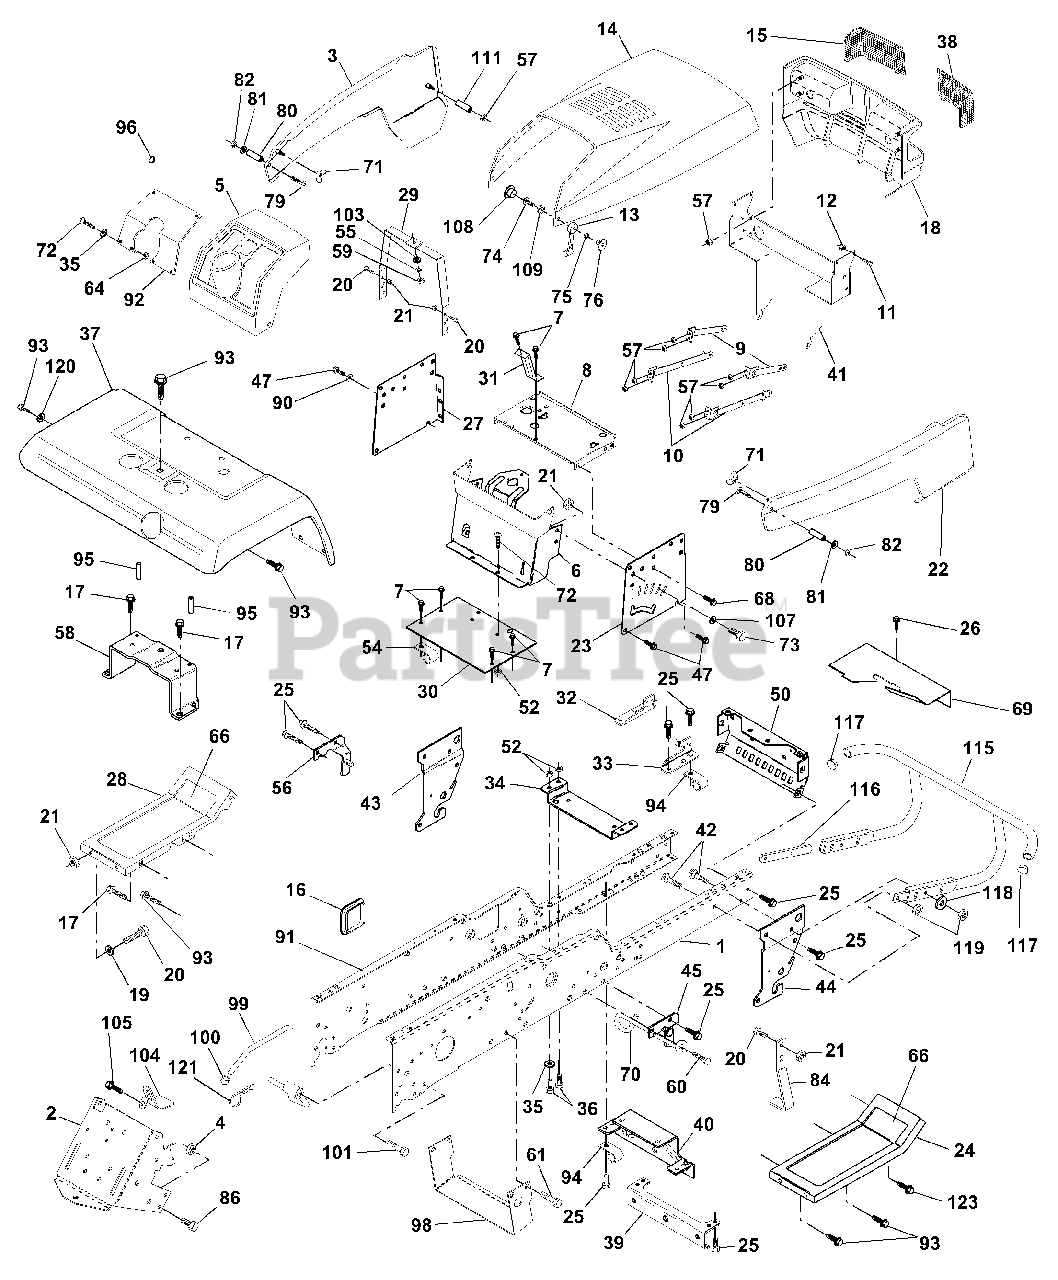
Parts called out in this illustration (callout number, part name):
1	Rail, Frame RH
2	Drawbar, Gt
3	Panel Asm., Side LH
4	Nut, Lock Hex 7/16 Unc
5	Dash, Plastic Black
6	Dash Asm., Lower
7	Screw, Thd Cut 1/4-20 x 1/2
8	Support, Battery
9	Strap, Asm. Hinge Front
10	Strap, Asm. Hinge Rear
11	Bolt Shoulder 1/4-20
12	Nut Crownlock 1/4-20
13	Latch, Chute Blk
14	Hood Asm., Pnt
15	Lens, Headlight LH
16	Cover, Access
17	Screw, Thdrol 3/8-16 x 3/4
18	Grille
19	Washer 13/32 x 13/16 x 12 Ga.
20	Bolt, Fin Hex 3/8-16 x 1
21	Nut, Lock Hex W/Wsh 3/8-16 Unc
22	Panel Asm., Side RH
23	Panel, Dash Side RH
24	Footrest, RH
25	Screw, Thdrol 3/8-16 x 3/4
26	Screw, Thdrol 5/16-18 x 3/4
27	Panel, Dash Side LH
28	Footrest, LH
29	Bracket, Support Dash
31	Brace, Support Steering
32	Bracket Asm., Frame Pivot Lh
33	Bracket Asm., Frame Pivot Rh
34	Bracket, Engine Support Rear
35	Washer 11/32 x 11/16 x 16 Ga.
36	Bolt, Fin Hex 5/16-18 x 3/4
37	Fender, Pnt.
38	Lens Headlight RH
39	Bracket, Axle Front
40	Bracket, Support Axle/Engine
41	Support Asm. Grille
42	Bolt, Carriage 3/8-16 x 1-1/4
43	Bracket, Spnsn Front Lh
44	Bracket, Spnsn Front Rh
45	Bracket Asm., Susp Chassis Rh
47	Screw Thdrol 3/8-16 x 1/2
50	Bracket, Chassis Front
52	Locknut, Hex W/Ins 5/16-18 Unc
54	Clip, Insulated
55	Washer 9/32 x 3/4 x 16 Ga.
56	Bracket Asm., Susp Chassis Lh
57	Nut Keps Hex 1/4-20
58	Bracket Asm., Fender
59	Nut Fin Hex 1/4-20
60	Screw Thdrol 3/8-16 x 1-1/4
61	Screw Thdrol. 3/8-16 x 3/4
62	Retainer Spring
64	Nut 5/16-18
66	Pad, Footrest
68	Screw, Thdrol 5/16-18 x 1/2
69	Shield, Heat
70	Guide, Belt Mid Span
71	Nut, Plastic Locking Wing 1/4-20
72	Screw, Mach Trhd 5/16-18 x 3/4
73	Bolt, Fin Hex 3/8-16 x 1 Gr. 5
74	Screw, Machine #10-24
75	Washer, Lock #10
76	Nut, Weld #10-24
79	Screw, Machine #10-24 x 1/4
80	Spacer, Split
81	Washer 7/32 x 1/2 x 18 Ga.
82	Nut #10-24
84	Stop, Over Center 44" 20/23" T. 94
86	Bolt, Fin Hex 7/16-14 Unc x 1
90	Washer, Lock External Tooth 3/8
91	Rail, Frame Lh
92	Plate, Silkscreen Dash
93	Screw, Thdrol 3/8-16 x 1/2
94	Clip, Fuel Line
95	Push Nut, Nylon
96	Plug, Hole
98	Bracket Chassis Skid
99	Rod Asm. Bypass
100	Cap Brake Parking Red
101	Screw Thdrol. 3/8-16 x 1-3/4
103	Washer, Lock 1/4
104	Bracket Lock Bypass
105	Screw Thdrol. 5/16-18 x 1/2
106	Screw Thdrol. Hex Hd Zinc Mur
107	Washer 13/32 x 1 x 14 Ga.
108	Cap, Snap Black
109	Cap, Washer Snap
115	Bumper Asm.
116	Bracket Extension Bumper
117	Plug Plastic
118	Washer 13/32 x 13/16 x 16 Ga.
119	Nut Crownlock 3/8-16 UNC
120	Washer 13/32 x 1 x 16 Ga.
